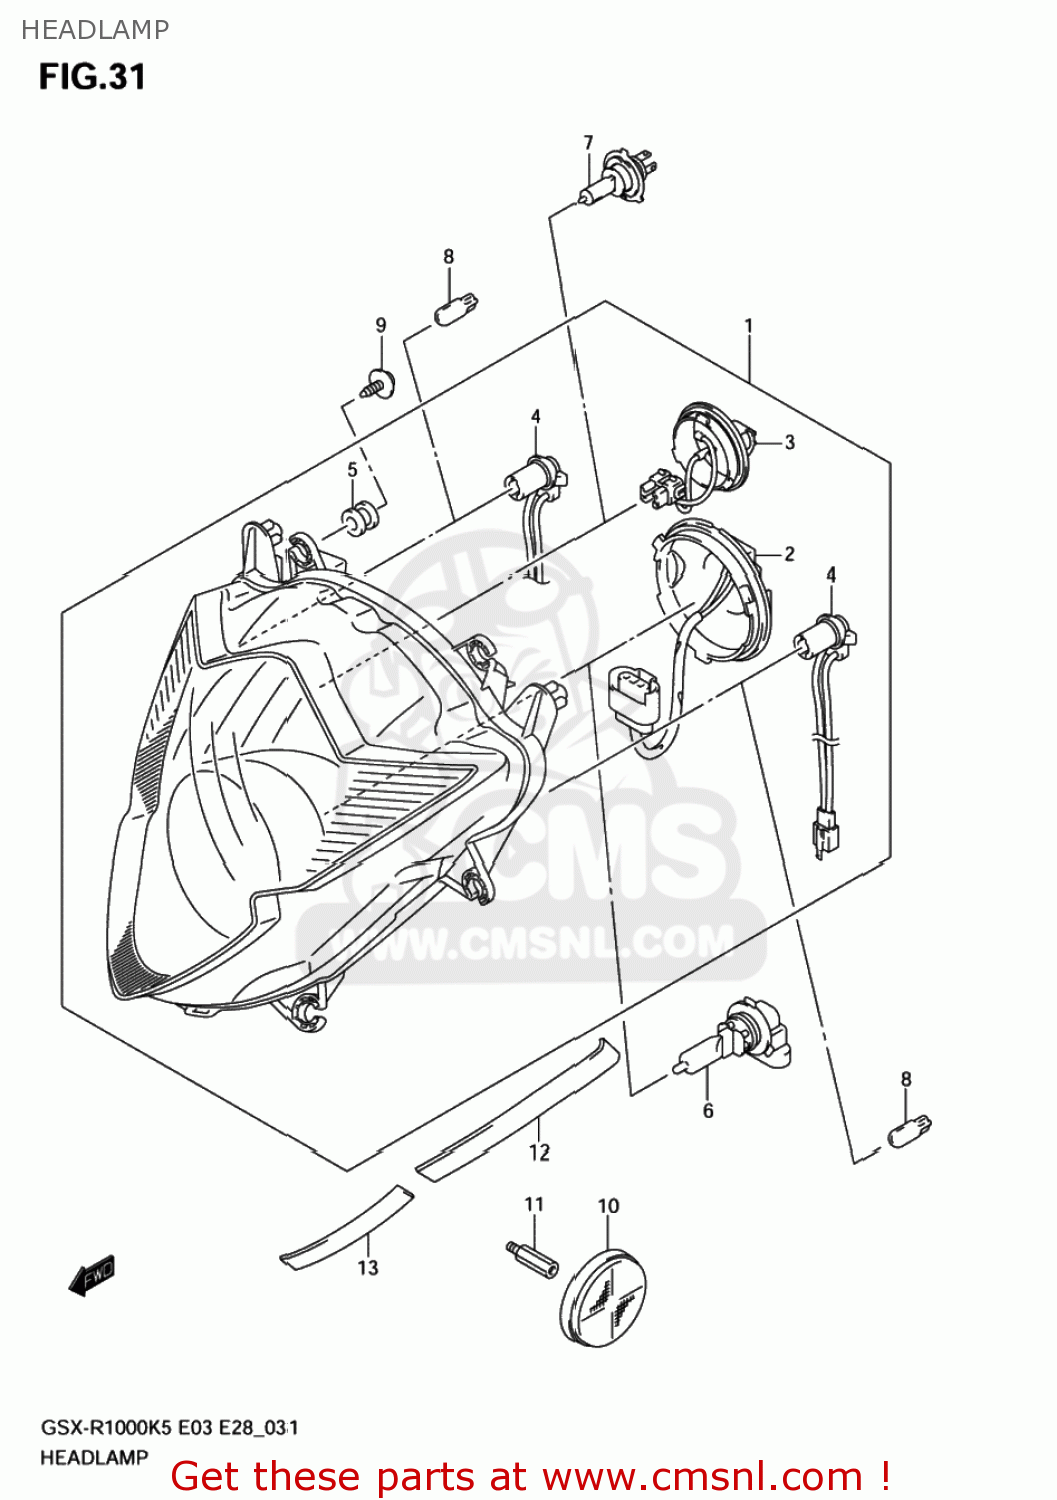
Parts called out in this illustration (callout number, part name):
1	HEADLAMP ASSY
2	BACK COVER,LWR
3	BACK COVER,UPR
4	CORD ASSY
5	CUSHION
6	BULB(12V60W,HB3,#9005)
7	BULB(12V55W/H7/PX26D/PHILIPS)
8	BULB(12V5W)
9	SCREW(5X15)
10	REFLECTOR,REFLEX FR
11	BOLT
12	TAPE,HEADLAMP LENS NO.1
13	TAPE,HEADLAMP LENS NO.2
